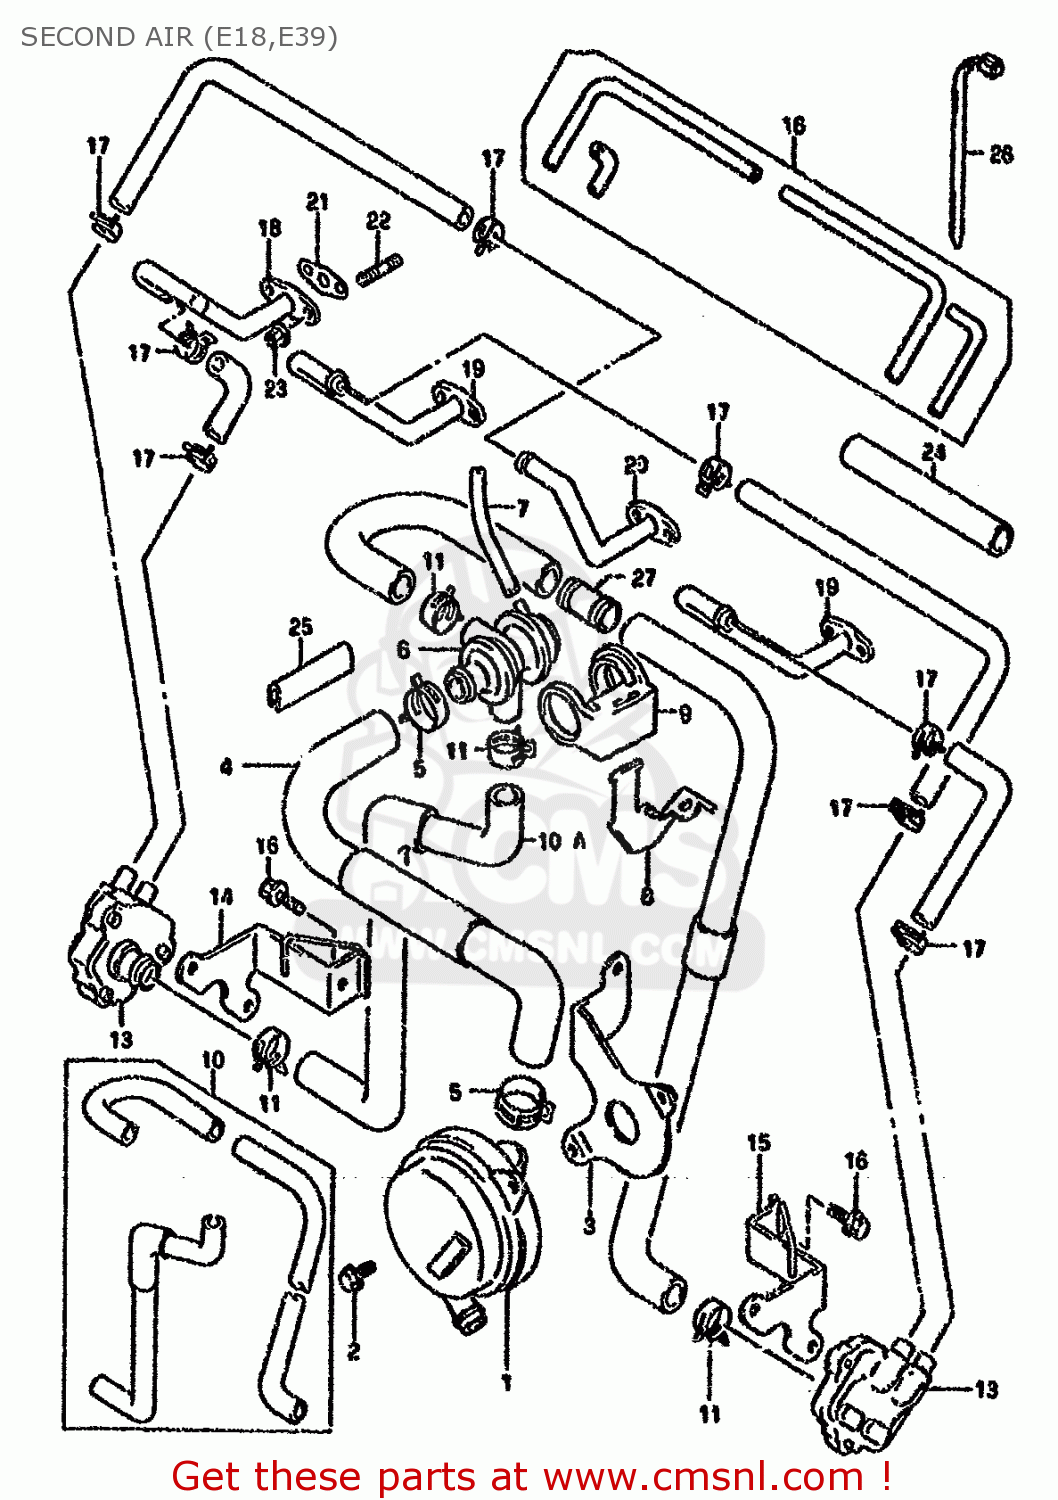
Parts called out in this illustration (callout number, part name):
1	CLEANER ASSEMBLY,SECOND AIR
2	BOLT
3	BRACKET,SECOND CLEANER
4	HOSE,SECOND AIR CLEANER
5	CLAMP
6	VALVE ASSY,2ND AIR SWITCHING
7	HOSE(4.5X8.5X600)
8	BRACKET,SECOND AIR VALVE
9	CUSHION,2ND AIR VALVE
10	HOSE SET,SECOND AIR NO.2
10A	HOSE,SECOND AIR VALVE NO
11	CLIP
12	VALVE ASSY,2ND AIR REED
13	BRACKET,REED VALVE,RIGHT
14	BRACKET COMP,REED VALVE
15	BOLT
16	HOSE SET,SECOND AIR NO.1
17	CLIP
18	PIPE,SECOND AIR NO.4
19	PIPE,SECOND AIR NO.1
20	PIPE,SECOND AIR NO.2
21	GASKET,SECOND AIR PIPE (N (NAS)
22	STUD BOLT
23	NUT
24	TUBE,FUEL HOSE
25	MOLDING,FUEL TANK RR
26	CLAMP(L:165)
27	UNION,SECOND AIR VALVE HOSE
